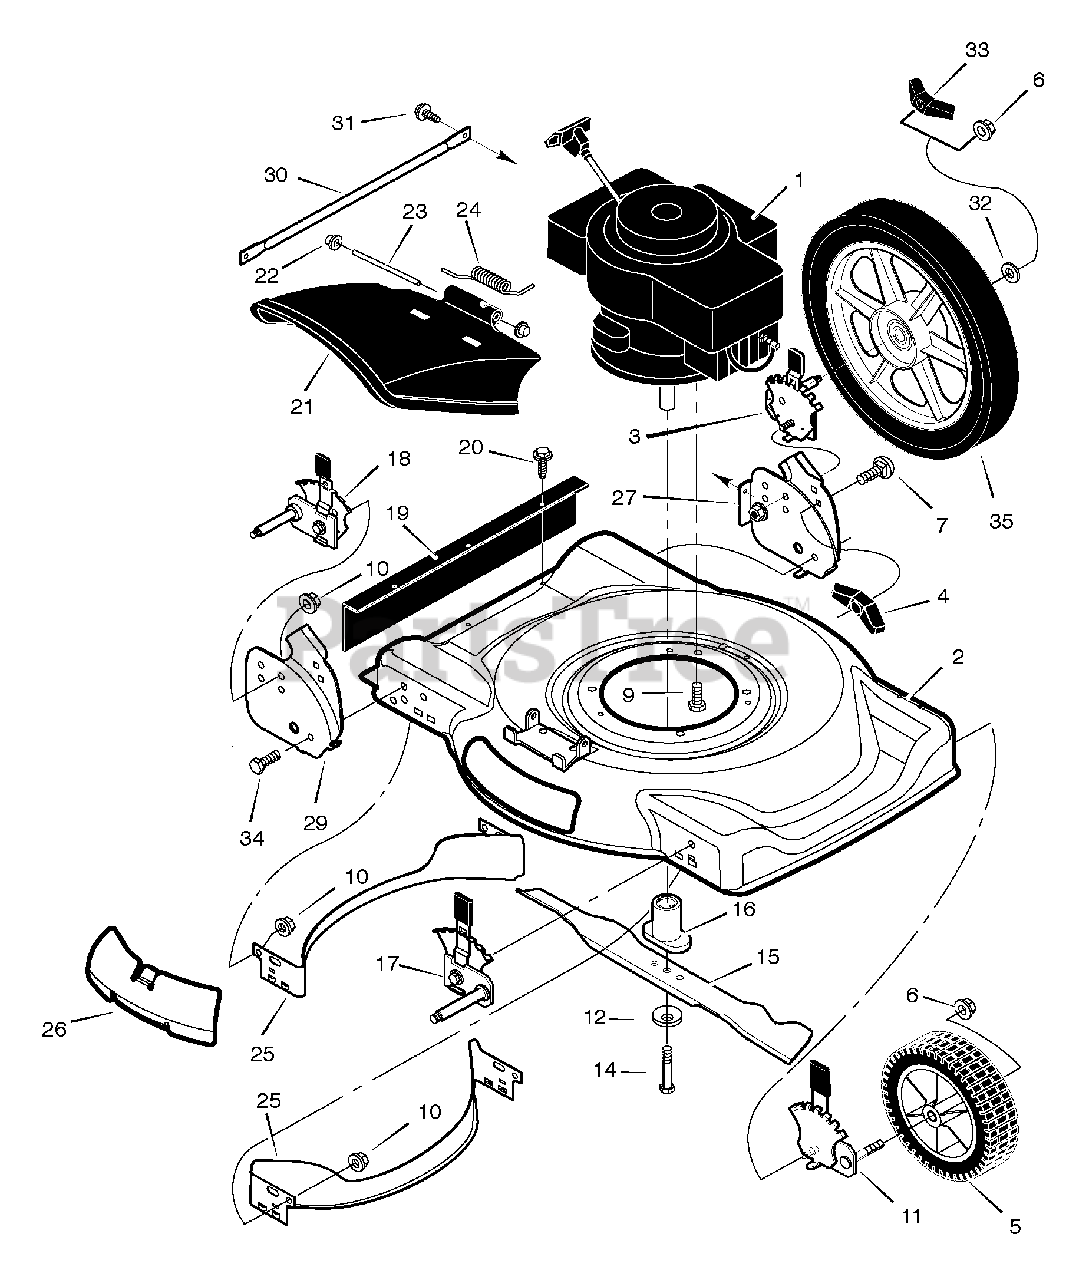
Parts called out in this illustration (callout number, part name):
1	Engine
2	Housing
3	Height Adjuster, Left Rear
5	Wheel and Tire, Front
6	Locknut, Flange
7	Bolt, Carriage
9	Bolt, Engine
10	Nut
11	Height Adjuster, Left Front
12	Washer, Belleville
14	Bolt, Hex
15	Blade
16	Adapter, Blade
17	Height Adjuster, Right Front
18	Height Adjuster, Right Rear
19	Guard, Rear
21	Deflector, Chute
22	Push-On Cap
23	Pin, Pivot
26	Plate, Mulcher
27	Bracket, Left Handle
29	Bracket, Right Handle
33	Knob, Axle
34	Bolt
35	Wheel and Tire, Rear
